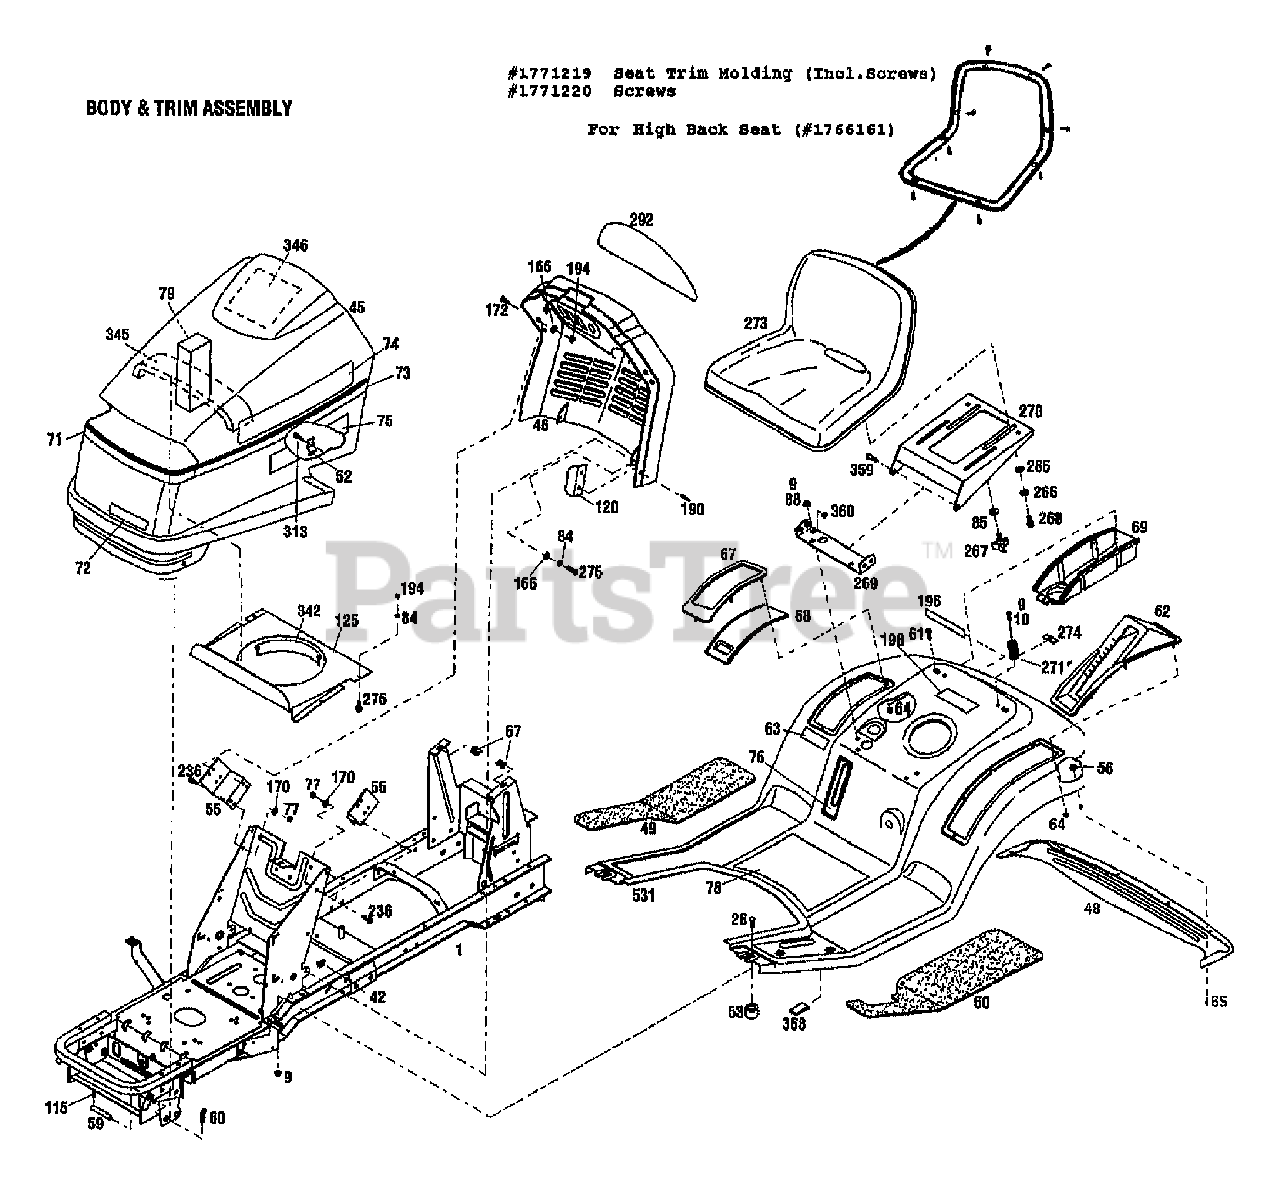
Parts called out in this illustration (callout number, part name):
9	NUT-HFLK 5/16-18 ZP
10	SCR-HHC 5/16-18X.75 GR 5 ZP
26	SCR-CARR 5/16-18X1.0 G2 ZP
42	NUT-SPEED
45	HOOD-TRACTOR
46	CONSOLE
48	TRIM-FENDER REAR
49	PAD-FOOT RH
50	PAD-FOOT LH
52	LATCH
53	SPACER-TUBULAR
55	BRKT-MOUNTING
56	NUT-HF/LK 1/4-20 ZP
59	PIN-PIVOT HOOD
60	PIN-HITCH .125X2.56 ZP
61	SCR-LOCK
62	COVER-LIFT HANDLE
63	DECAL-AMERICAN LEGEND-LRG
64	NUT-SELF THRD 1/4
65	SCR-HH 1/4-20X.625
67	TOP-STORAGE COVER
68	COVER-CONTAINER
69	CONTAINER-STORAGE
71	DECAL-STRIPE HOOD FRONT
72	DECAL-LOGO
73	DECAL-STRIPE SIDE
74	DECAL-LOGO TROY-BILT
75	DECAL-MODEL 13039 {13039}
75	DECAL-MODEL 13040 {13040}
76	DECAL-FUEL LEVEL
77	NUT-HEX 5/16-18 ZP
78	DECAL-OPER INST
79	BLOCK-SEALING
84	WASHER-LK .25 ZP
85	WASHER-FLAT 3/8 SAE
88	SCR-CARR 5/16-18X.62 G2 ZP
115	PIN-ROLL .188X1.0
120	BRKT-HOOD ALIGN
125	SHIELD-HEAT UPPER
166	WASHER-FLAT 1.25X.28X.062 ZP
170	WASHER-LK .312 ZP
190	RIVET-POP
194	NUT-HEX 1/4-20 ZP
196	DECAL-LOGO FENDER
198	DECAL-FUEL
236	SCR-HFLK 5/16-18X.75 ZP
265	WASHER-1.06X.51X.09 NYLON
266	WASHER-BOW .74X.52X.01
268	SCR-SHLDR 3/8-16X.25 G5ZP
270	SUPPORT-SEAT
271	SPRING-COMPRESSION
273	KIT-SEAT (TRACTOR)
274	BRKT-SPRING HOLD DOWN
275	SCR-HH 1/4-20X.625 G5 ZP
292	LENS-INSTRMTS WARN LIGHTS {13040}
292	LENS-INSTRMTS WARN LIGHTS {13039}
342	GASKET-HEAT SHIELD
345	STRIP-SEALING
346	DECAL-SERVICE
359	SCR-HH 3/8-16X.88 G5 ZP
360	NUT-H/LK 3/8-16
531	FENDER-RED W/DECALS
